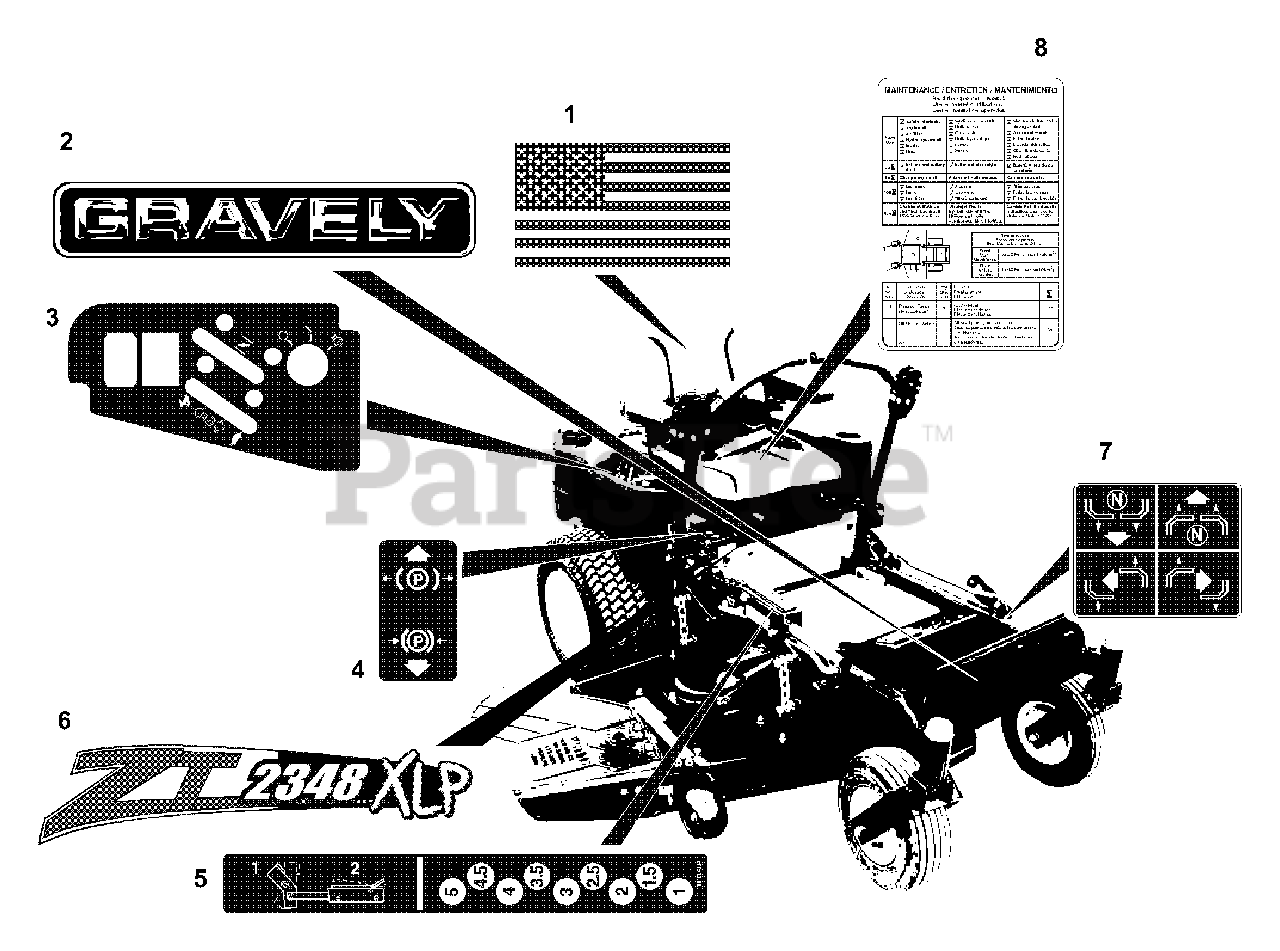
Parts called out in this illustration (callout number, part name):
1	Decal, American Flag
2	Decal, Gravely Logo
3	Decal, Control Panel
4	Decal, Parking Brake Lever
5	Decal, Height of Cut
6	Decal, ZT 2348XLP
6	Decal, ZT 2044XLP
7	Decal, Instructional Steering
8	Decal, Maintenance Instructions
